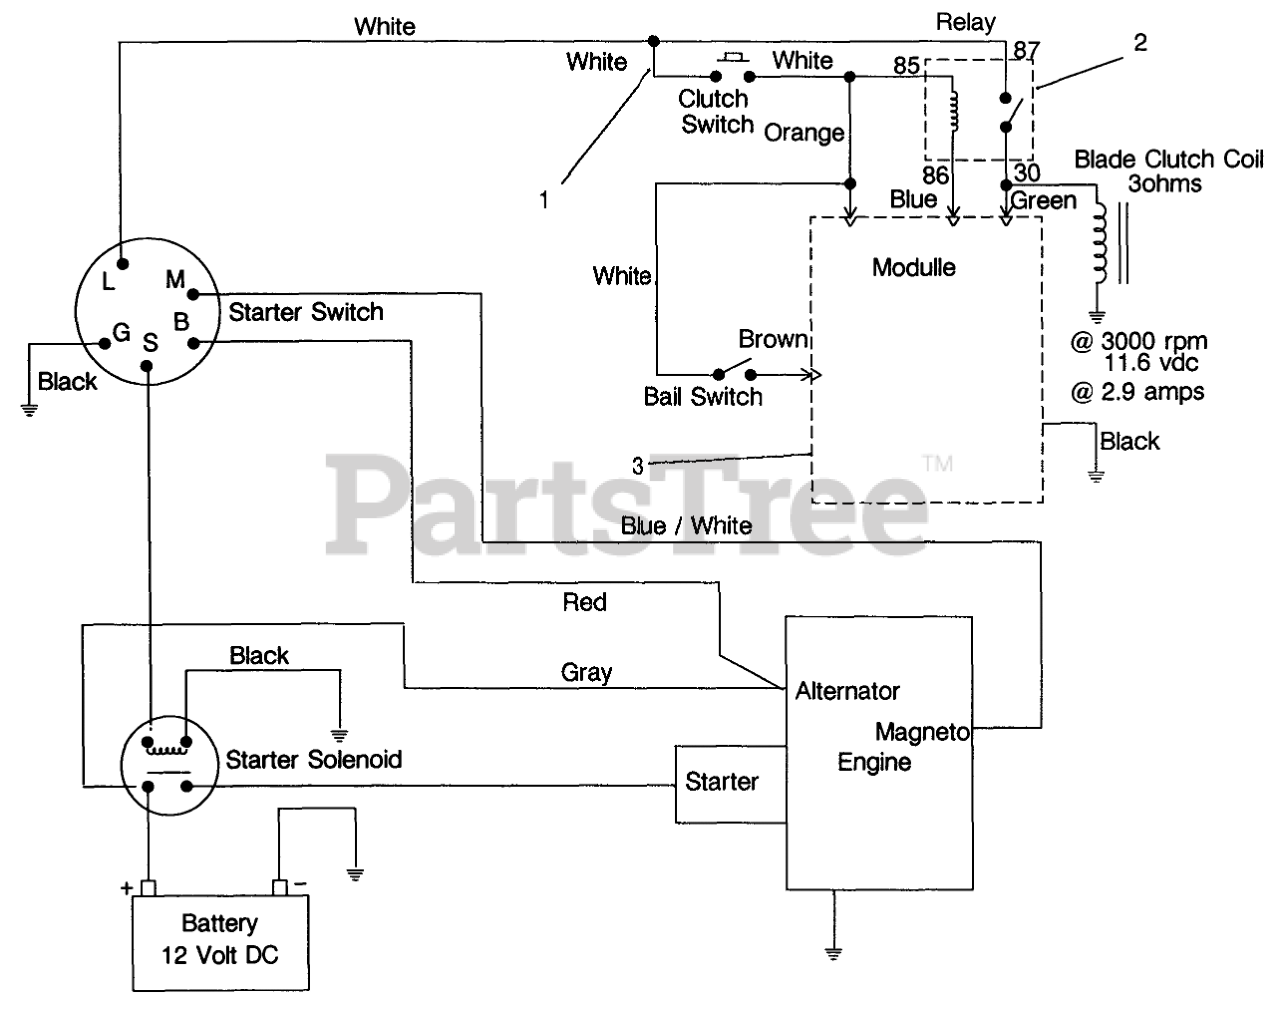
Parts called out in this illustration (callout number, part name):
1	Wire HARness
2	Relay
3	Module
